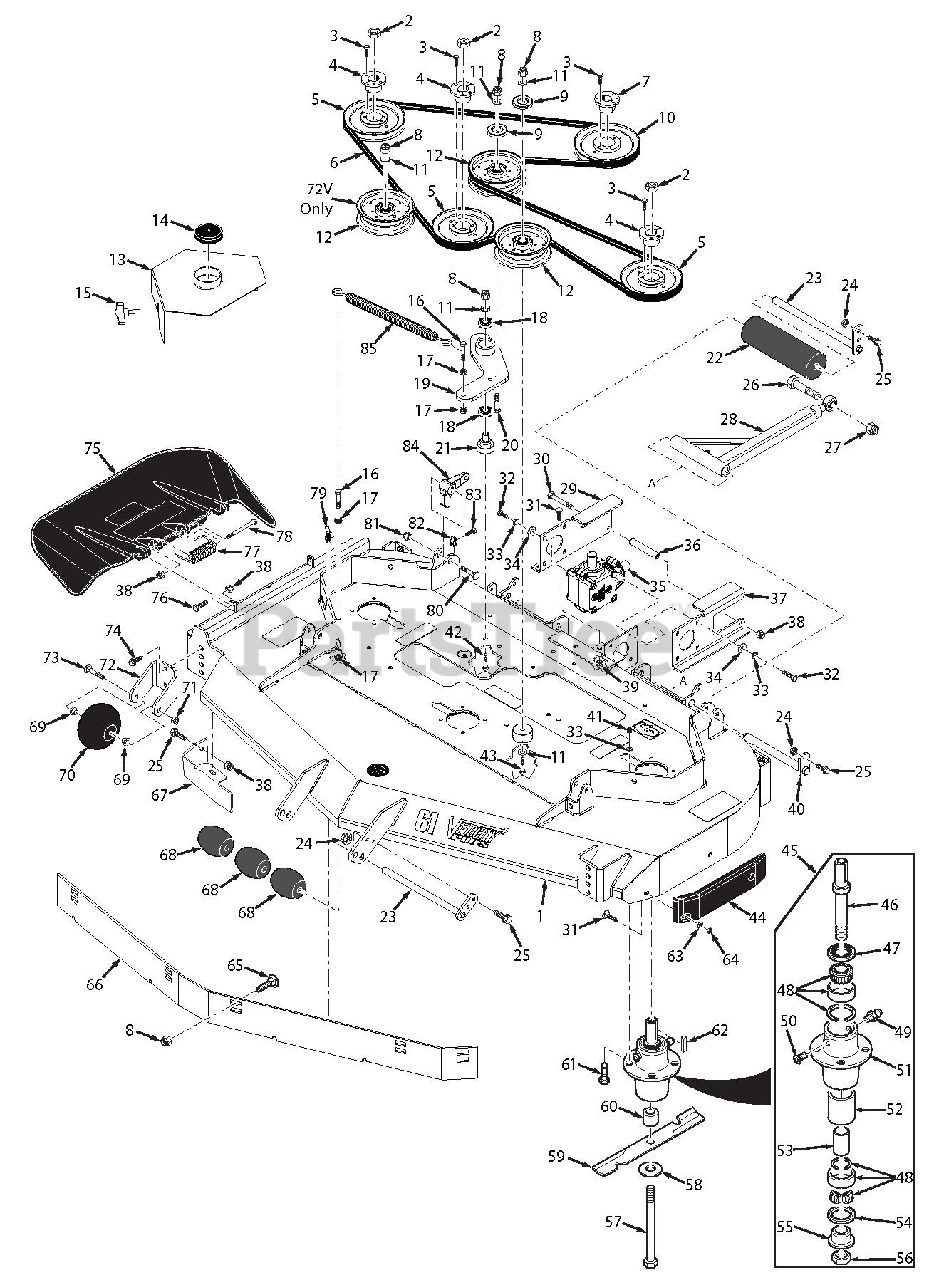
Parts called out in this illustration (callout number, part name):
1	Cutter Deck w/Decals - 61V
1	Cutter Deck w/Decals - 72V
2	Nut, 5/8-11 UNC
3	Bolt, Hex Head 1/4-20 x 1" Grade 8
4	Tapered Hub, 1-1/8" Bore
5	Pulley, 6.35 O.D.
5	Pulley, 6.95 O.D.
6	Belt, Deck Drive - 61V
6	Belt, Deck Drive - 72V
7	Tapered Hub, 1" Bore
8	Nut, Elastic Stop 3/8-16
9	Dust Shield
10	Pulley, 6.75 O.D.
10	Pulley, 6.35 O.D.
11	Flatwasher, 3/8-.391 x .938 x .105 HD
12	Pulley, Idler
13	Belt Cover, 61V
13	Belt Cover, LH 72V
13	Belt Cover, RH 72V
14	Cap, Spindle
15	Knob w/Stud
16	Bolt, Hex Head 3/8-16 x 1-1/2" Grade 8
17	Nut, Serrated Flange 3/8-16
18	Bearing
19	Idler Arm Assy.
20	Bolt, Hex Head 3/8-16 x 2-3/4"
21	Pivot, Idler
22	Guide Roller
23	Roller Shaft
24	Nut, Serr. Flange 5/16-18
25	Bolt, Hex Head 5/16-18 x 1"
26	Bolt, Hex Head 5/8-11 x 4-1/2"
27	Nut, Elastic Stop 5/8-11
28	Pusharm Assy., LH
28	Pusharm Assy, RH
29	Mounting Plate
30	Bolt, Hex Head 5/16-18 x 4-3/4"
31	Bolt, Carriage 5/16-18 x 3/4"
32	Bolt, Hex Head 5/16-18 x 1"
33	Lockwasher, 5/16"
34	Flatwasher, 5/16-.375 x .875 x .083
35	Gearbox
36	Spacer
37	Mounting Plate
38	Nut, Elastic Stop 5/16-18
39	Nut, Serr. Flange 5/16-18
40	Shaft Weldment, Pusharm
41	Nut, Elastic Stop 5/16-18 Grade 8
42	Bolt, Hex Head 3/8-16 x 3"
43	Bolt, Hex Head 3/8-16 x 3-3/4"
44	Pad, Deck Wear
45	Spindle Assembly
46	Shaft, Spindle
47	Seal, Top
48	Bearing Assembly
49	Grease Fitting
50	Relief Fitting, Tapered Spindle
51	Spindle Housing
52	Spacer, Outside
53	Spacer, Inside
54	Seal, Bottom
55	Spindle Bushing, Bottom
56	Nut, Special 1-1/16 - 18
57	Bolt, Hex Head 5/8-11 x 9-1/2
58	Flatwasher, 5/8-.688 x 1.75 x .134 HD
59	Cutter Blade, 21"
59	Cutter Blade, 21" (35BV)
59	Cutter Blade, 24-1/2"
60	Spacer, Spindle Bottom
61	Bolt, Hex Head 5/16-18 x 1-3/4" Grade 8
62	Key, 1/4 x 1/4 x 2"
63	Flatwasher, 5/16-.344 x .688 x .065
64	Nut, Center Lock 5/16-18
65	Bolt, Carriage 3/8-16 x 1"
66	Baffle, Custom Cut - 61V
66	Baffle, Custom Cut - 72V
67	Baffle, Turbo - 61V
67	Baffle, Turbo - 72V
68	Wheel, Anti-Scalp
69	Bushing, .376 I.D. Oilite
70	Anti-Scalp Wheel
71	Nut, Center Lock 3/8-16
72	Bracket, Anti-Scalp
73	Bolt, Carriage 3/8-16 x 4"
74	Bolt, Hex Head Serr. Flange 3/8-16 x 1"
75	Discharge Chute Assy.
76	Bolt, Hex Head 5/16-18 x 1-3/4"
77	Spring, Discharge Chute
78	Bolt, Hex Head 5/16-18 x 4-3/4"
79	U-Nut, 3/8-16
80	Bolt, Carriage 7/16-14 x 2-1/4"
81	Nut, Elastic Stop 7/16-14
82	U-Nut, 3/8-16 (short)
83	Bolt, Hex Head 3/8-16 x 2" Special
84	Lever, Deck Level
85	Spring
